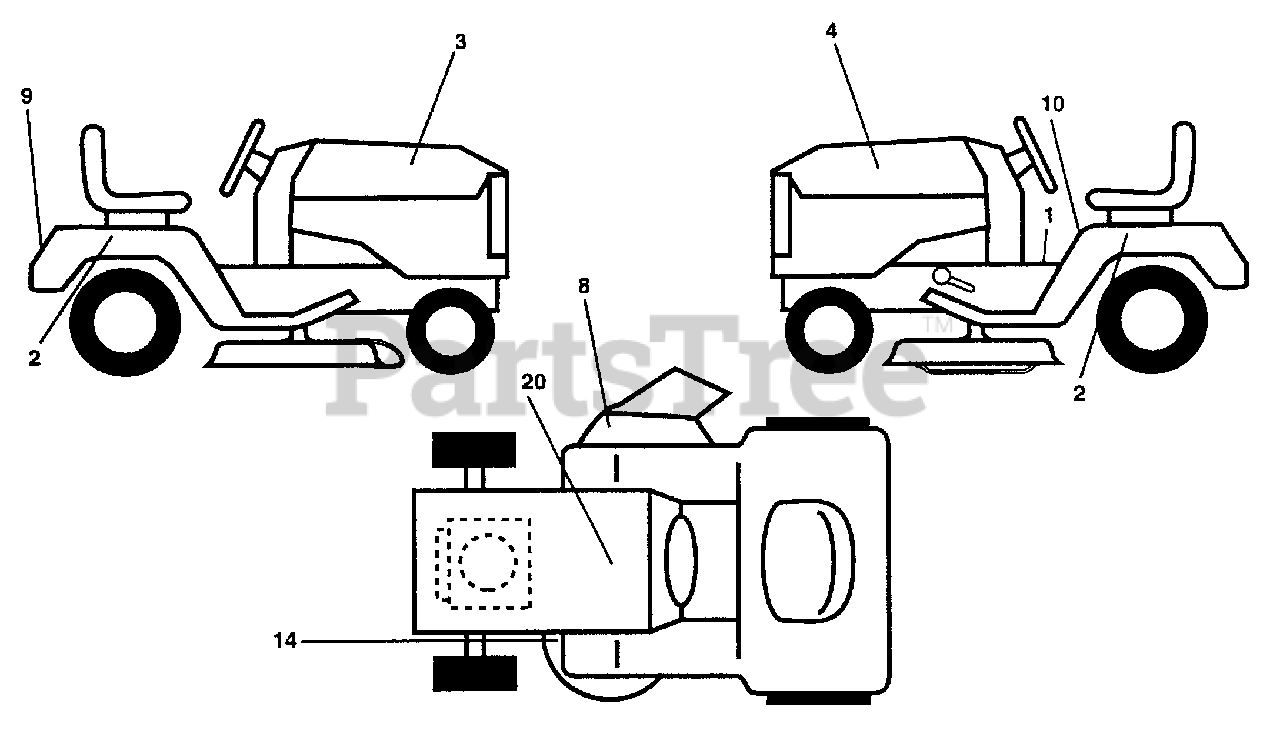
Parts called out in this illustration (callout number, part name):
1	Decal Oper Step Thru E/F
2	Decal Fender Auto Husq. Radius
3	Decal Hood LH
4	Decal Hood RH
8	Decal Warning
9	Decal Fender Husq
10	Decal Fender Danger E/F
14	Decal V-Belt Schematic
20	Decal Bat Dan/Psn
